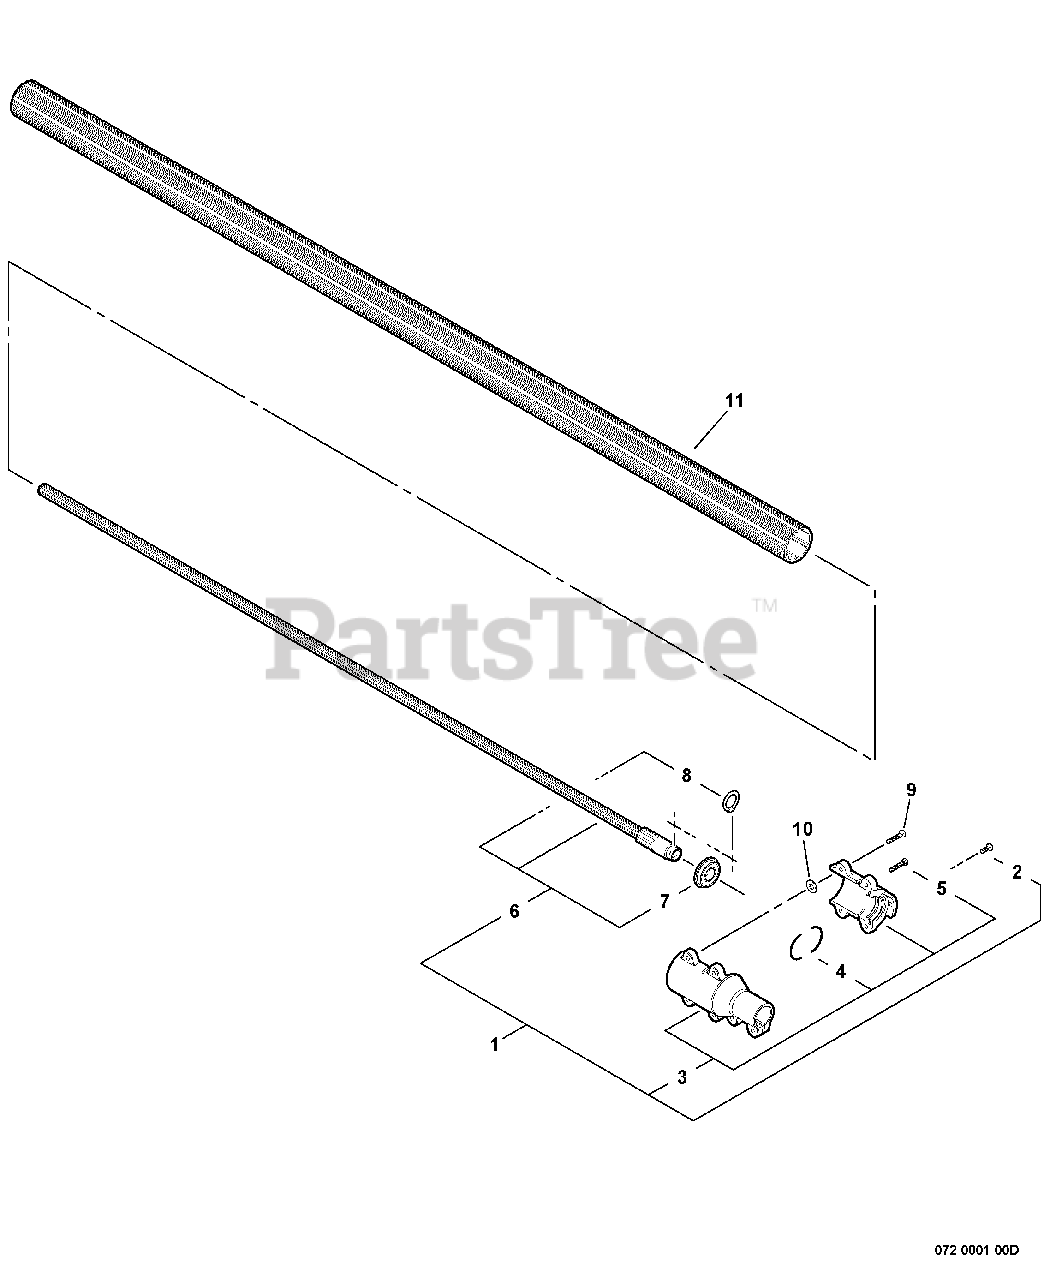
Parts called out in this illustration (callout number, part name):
1	COUPLING/DRIVESHAFT KIT
2	BOLT 5×14
3	COUPLING ASSY, LOWER
4	CUSHION
5	BOLT 5×20
6	DRIVESHAFT ASSY, LOWER
7	BEARING, BALL 15×32×9
8	RING, RETAINING
9	BOLT 5×20
10	WASHER 5
11	PIPE, MAIN - ORANGE
